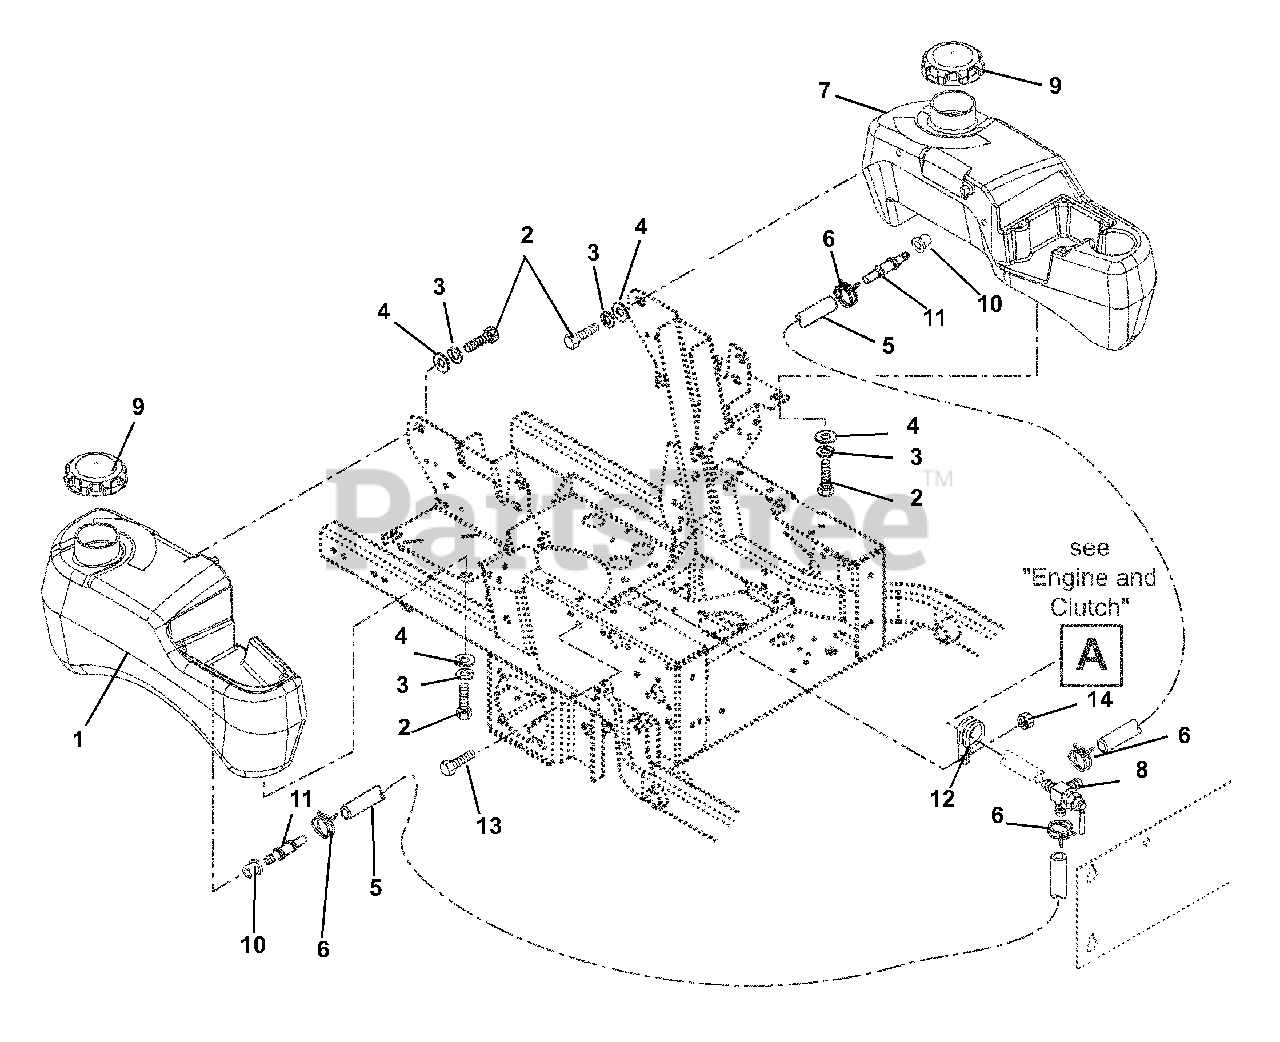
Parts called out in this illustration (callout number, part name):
1	Tank, Gas - Right Hand
2	Bolt, Hex .31-18 x .75 Grade 5
3	Washer, Locking .31 x .078
4	Washer, Flat Steel .38 x .875 x .083
5	Gas Line, Bulk .25" ID
6	Hose, Clamp
7	Tank, Left Hand Fuel (EYE-Q) 100 Series
8	Valve, Fuel
9	Cap, Gas
10	Bushing
11	Fuel Tank Fitting
12	Clamp, Cushioned Steel (081, 082)
13	Bolt, Hex .38-16 x 1.00 Grade 5 (081, 082)
14	Nut, Locking Top Flange .38-16 (081, 082)
